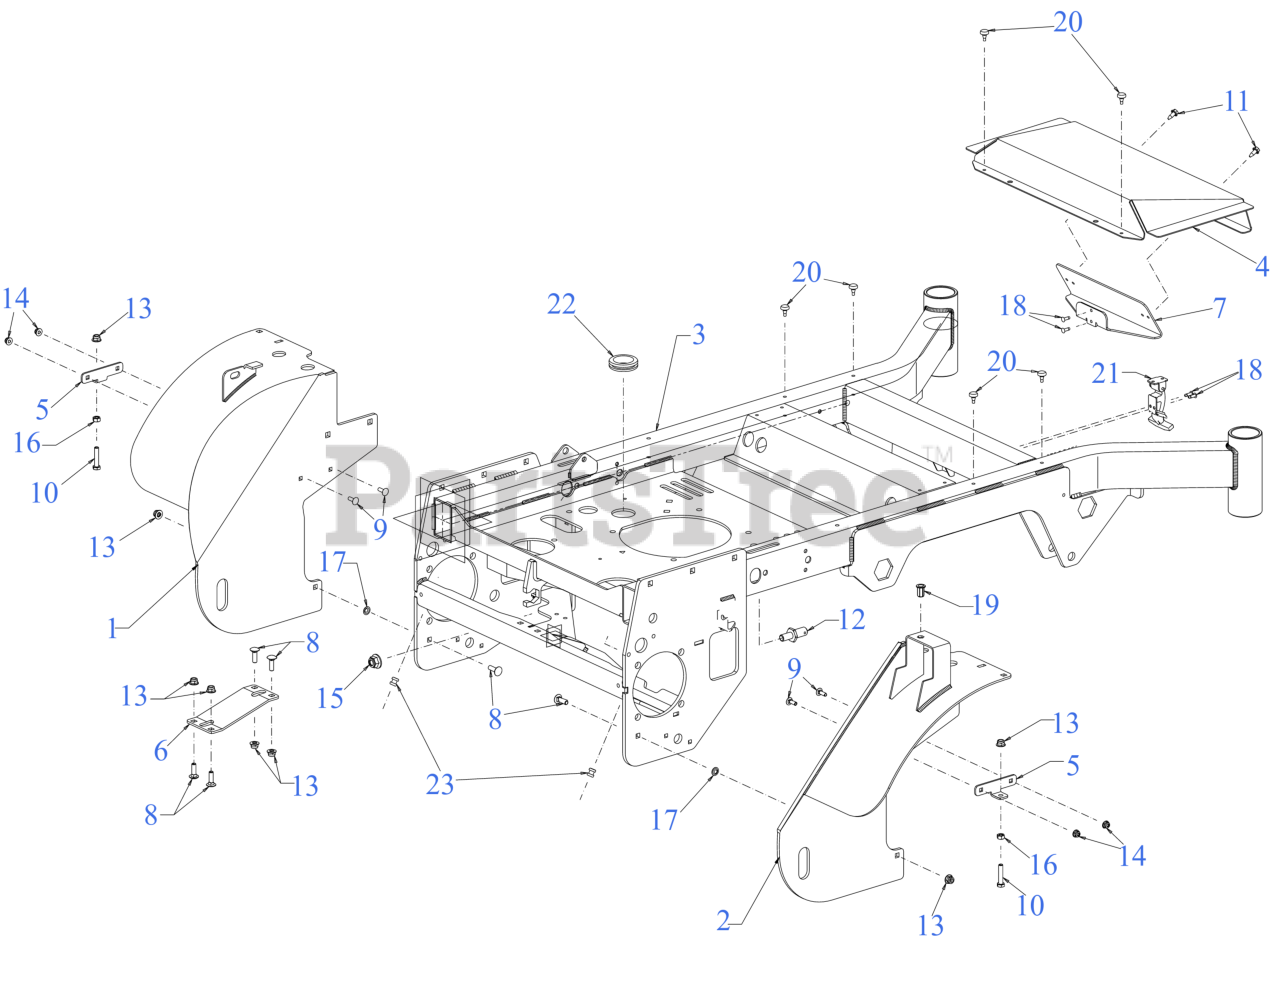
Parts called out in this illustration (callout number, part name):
1	FENDER (LH)
2	FENDER (RH)
3	FRAME
4	FRONT COVER
5	BRAKE SPRING BRACKET (RH)
6	SUPPORT BRACKET
7	BACK PLATE
8	CARRIAGE BOLT 5/16-18 x 1.00
9	SCREW 1/4-20 x .75 GR5
10	SCREW 5/16-18 x 1.5 LG
11	SCREW 1/4-20X.625
13	FLANGE LOCK NUT 5/16-18
14	FLANGE LOCK NUT
16	HEX NUT 5/16-18
18	POP RIVET
19	RIV NUT 3/8-16
20	RUBBER BUMPER
21	HOOD LATCH ASSEMBLY
22	RUBBER GROMMET (1.50X2.13X.563)
